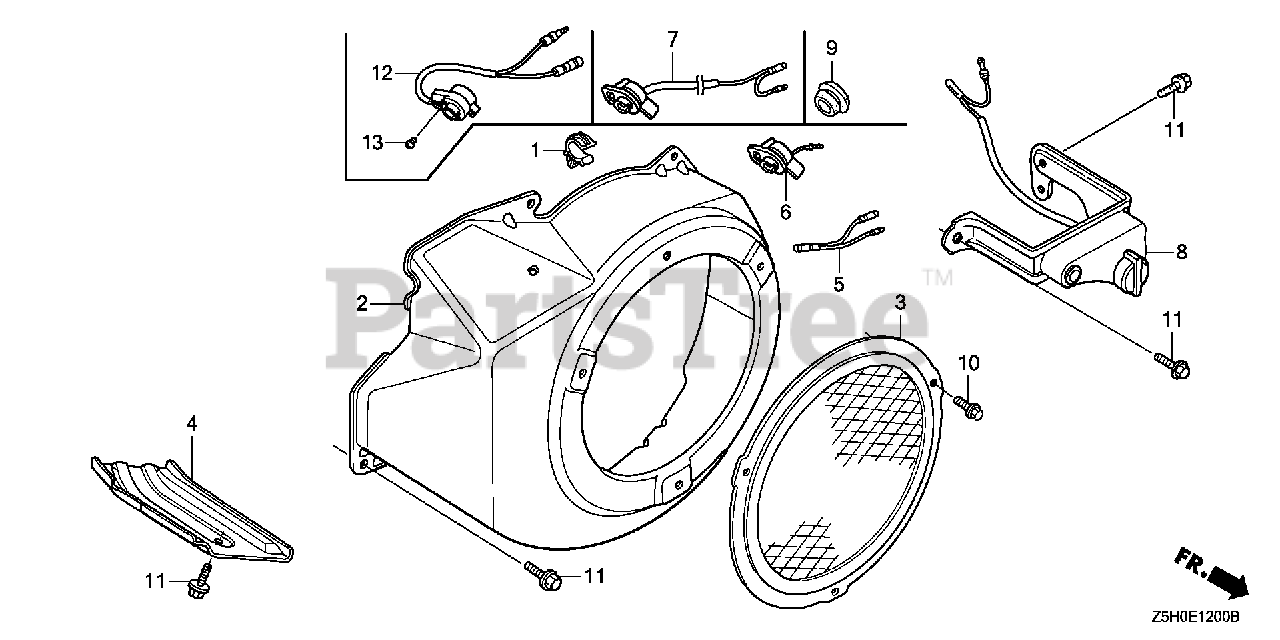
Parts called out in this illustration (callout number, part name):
1	CLIP, TUBE
2	COVER, FAN *R280* (POWER RED)
9	GROMMET, DRAIN HOLE
11	BOLT, FLANGE (6X12) (CT200)
